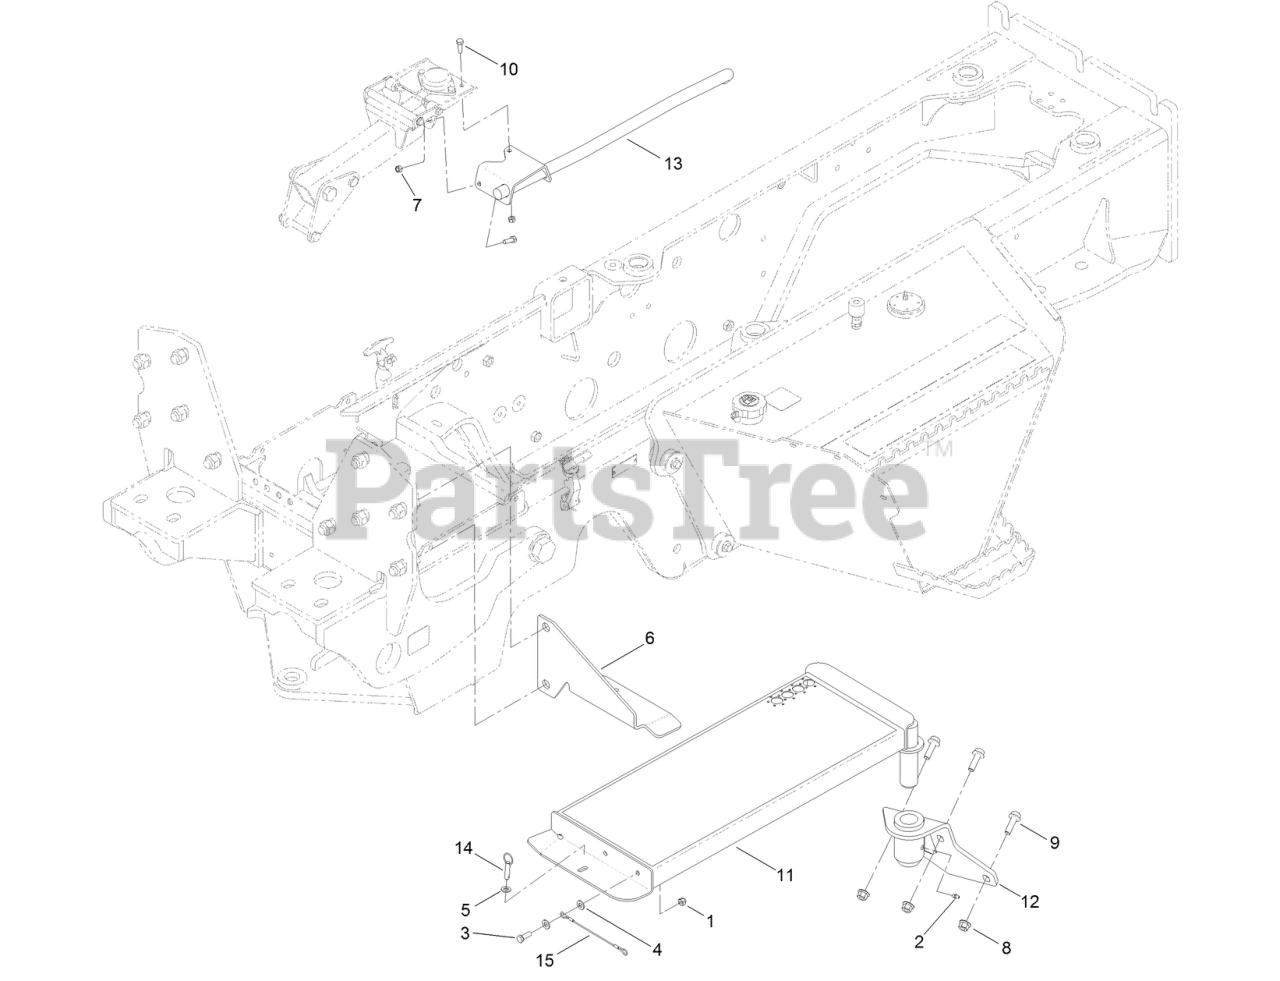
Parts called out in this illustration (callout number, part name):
1	NUT-HEX
2	FITTING-GREASE
3	SCREW-HH
4	WASHER-FLAT
5	WASHER-FLAT
6	BRACKET-SUPPORT, WALKWAY
7	NUT-LOCK, NI
8	NUT-LOCK, HHF
10	SCREW-HH
11	WALKWAY-BACKHOE
12	MOUNTING-BRACKET, WALKWAY
13	HANDRAIL-BACKHOE
14	PIN-COTTERLESS
15	RETAINER-ROPE, WIRE
